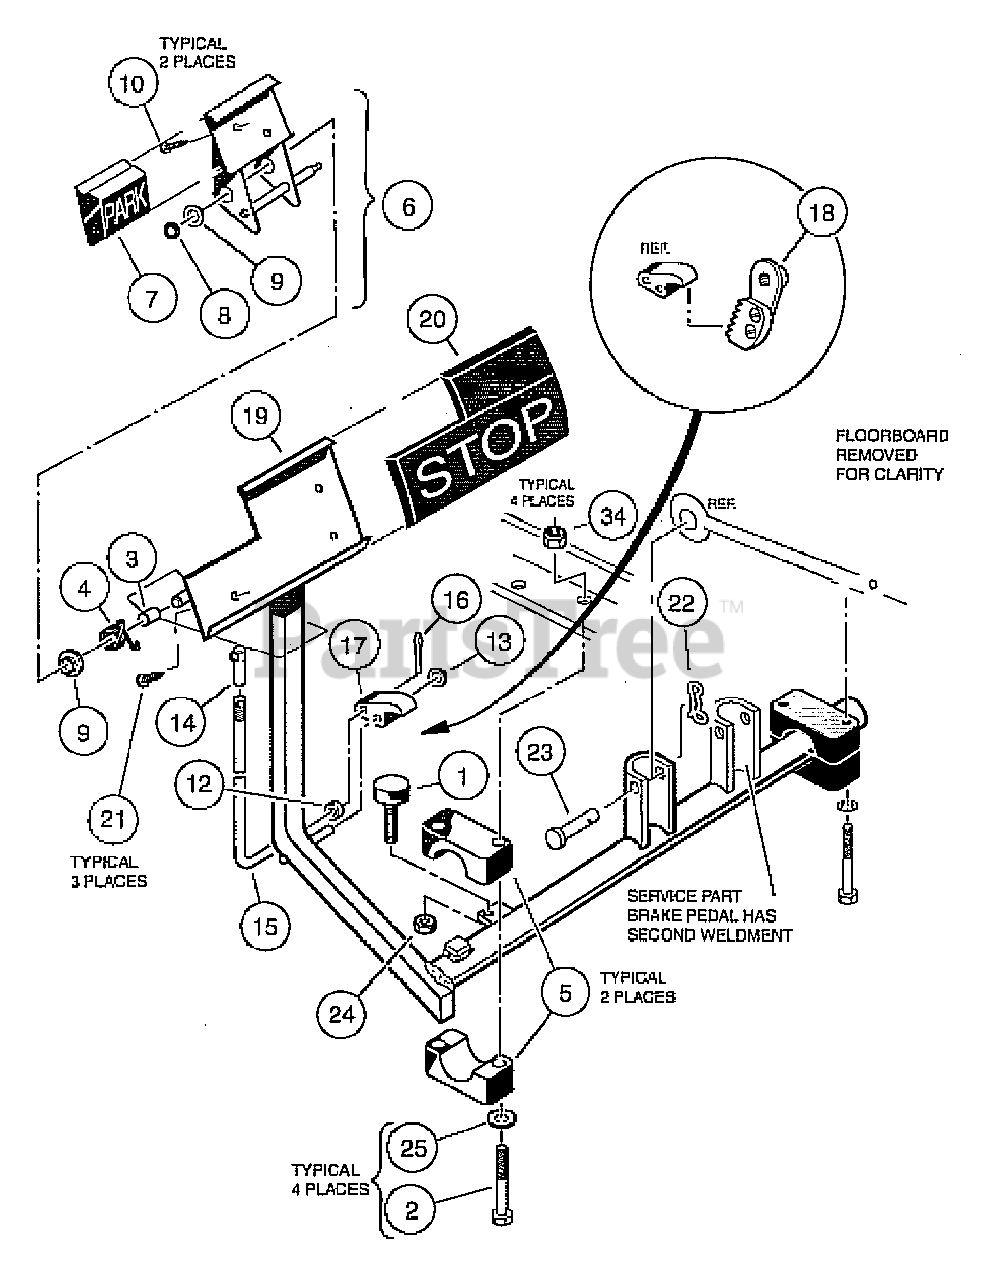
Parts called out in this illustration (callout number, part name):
1	Bumper, Brake Pedal Rubber
2	Screw, 5/16-18 X 2.50 Hex Cap
3	Hill Brake Spacer
4	Spring, Hill Brake Torsion
5	Package, Brake Mounting Block
6	Kit, Hill Brake Pedal
7	Pad, Hill Brake
8	Pushnut, 3/8
9	Bushing, Nylon
10	Screw, #10-16 Type Ab Sht Mtl
11	Kit, Hill Brake Latch
12	Sleeve, Hill Brake Rod
13	Pushnut, 3/8
14	Ball Joint, 1/4-28
15	Rod, Hlll Brake
16	Pin, Cotter, 7/64 x 1/2 Stainless-Steel
17	Pawl, Hill Brake
18	Ratchet Assembly
19	Brake Pedal Kit
20	Pad, Brake Pedal
21	Screw, #10-16 Type Ab Sht Mtl
22	Pin, Bow Tie Locking
23	Pin, 3/8 X 1-5/16 Clevis
24	Nut, 1/4-20 Hex
25	Washer, 5/16 Type A Flat
